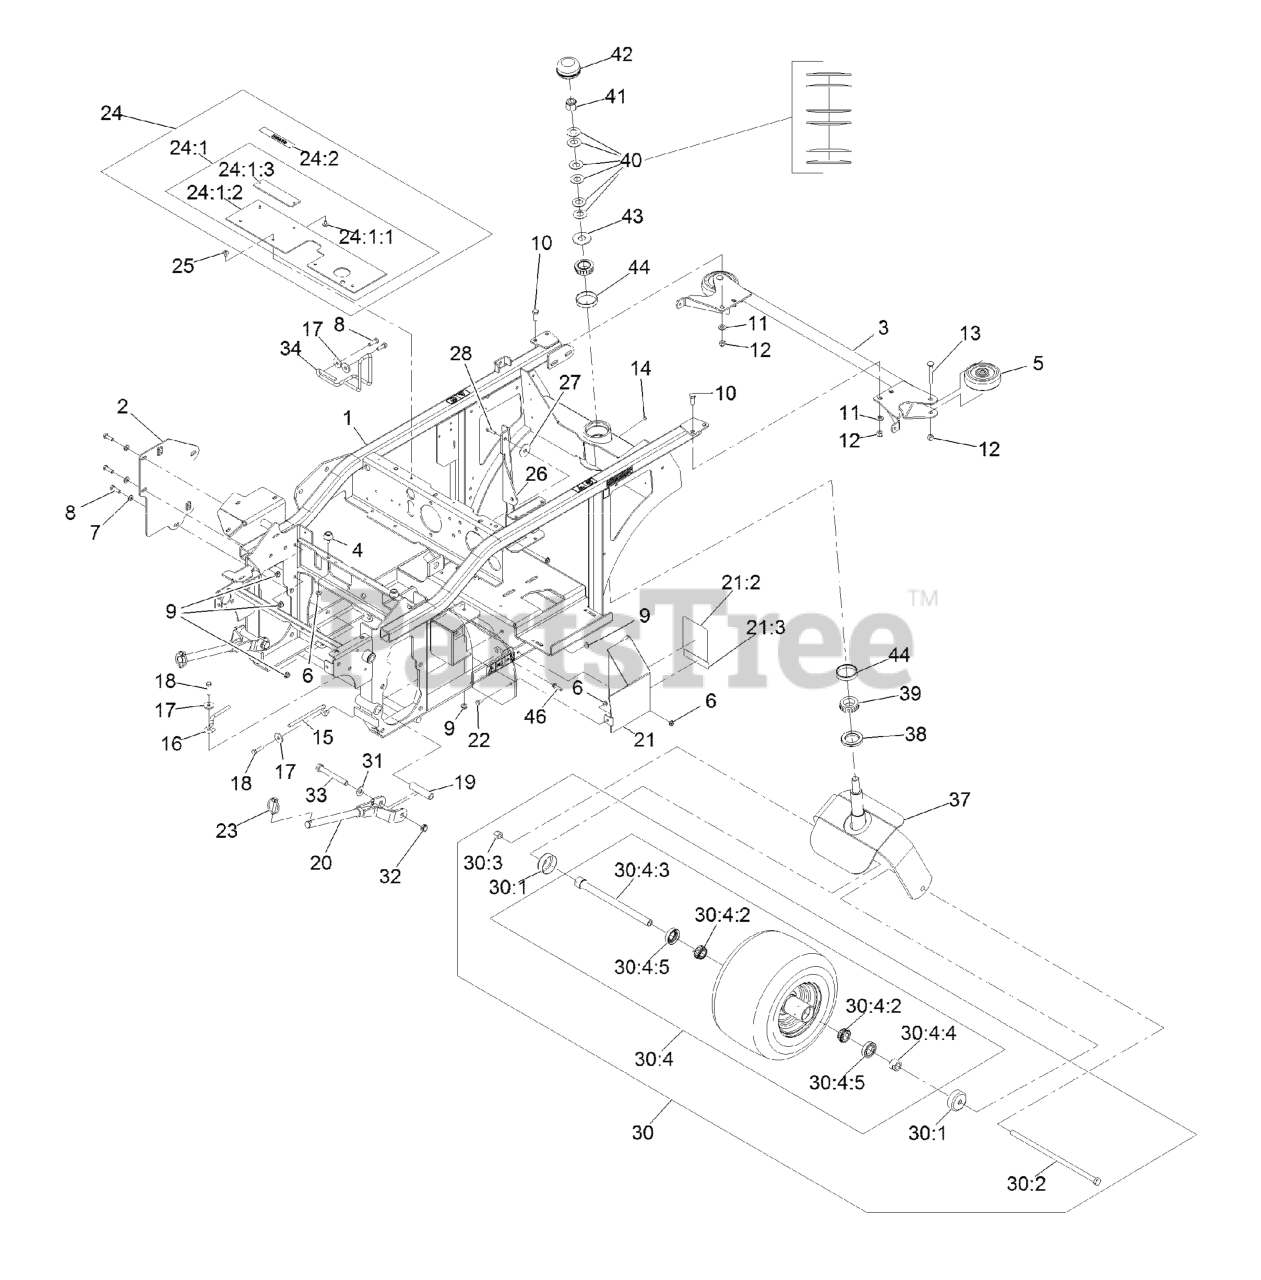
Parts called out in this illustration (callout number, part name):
1	FRAME ASM
2	PLATE-SUPPORT
3	BUMPER-REAR
4	BUMPER-RUBBER
5	ROLLER-BUMPER
7	WASHER-PLAIN
8	SCREW-HH
10	SCREW-HH
11	WASHER-FLAT
12	NUT-LOCK, NI
13	SCREW-CARR
15	GUIDE-BELT
16	GUIDE-BELT
18	SCREW-HH
19	SPACER-WHEEL, SHORT
21	DRIVE SHIELD ASM
21:2	Decal-Belt Routing
21:3	DECAL-WARNING
22	SCREW-HH
23	PIN-LYNCH
24	LIFT SHIELD ASM
24:1	Shield-Lift
24:1:1	RIVET-POP
24:1:3	Plate-Decal
24:2	DECAL-WARNING
25	RIVET-POP
26	BRACE-PTO
28	SCREW-HH
30	REAR CASTER WHEEL ASM
30:1	GUARD-SEAL
30:2	SCREW-HH
30:3	NUT-LOCK, NI
30:4	ASM,WHEEL,TIRE & BRG SP
30:4:2	BEARING-CONE, TAPERED ROLLER
30:4:3	AXLE CASTER ASM
30:4:4	SPACER-NUT
30:4:5	SEAL-CASTER
31	WASHER-FLAT
32	NUT-HEX
33	SCREW-HH
34	GUIDE-BELT
37	FORK-REAR CASTER
38	SEAL-GREASE
39	BEARING-ROLLER, CONE TAPE
40	WASHER-BELLVILLE
41	NUT-LOCK, NI
42	CAP-GREASE
43	WASHER-FLAT
44	CUP-TAPERED, ROLLER BEARI
45	SHIELD-HEAT
46	SCREW-HHF
